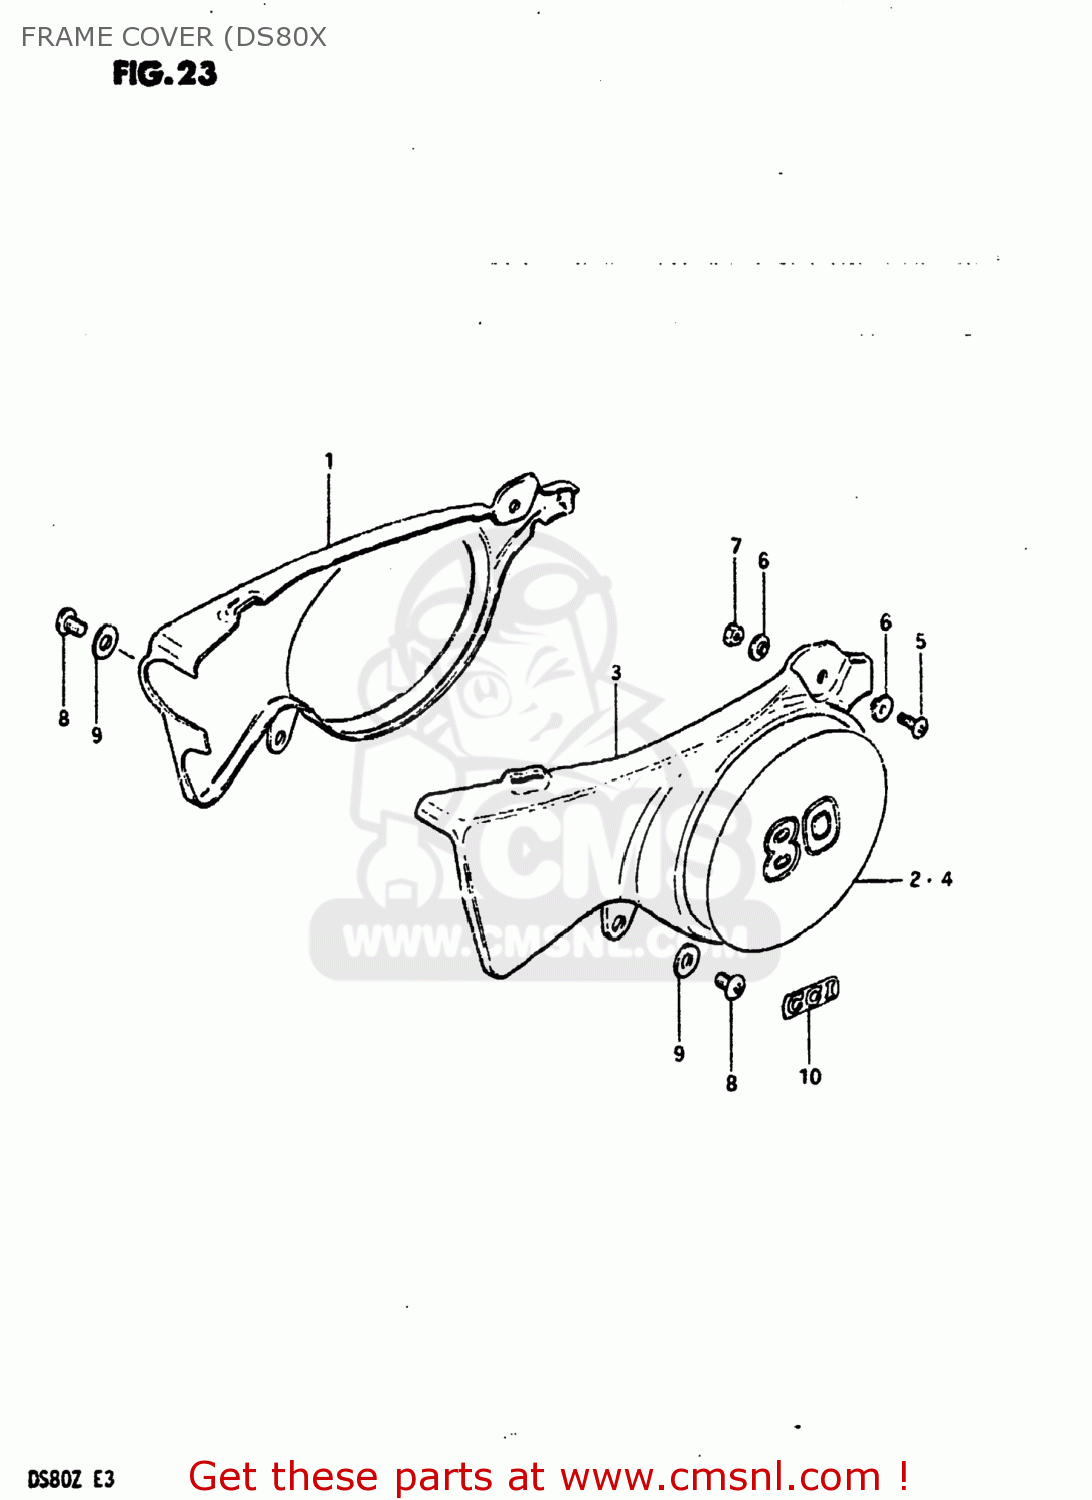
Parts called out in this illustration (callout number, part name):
1	COVER,FRAME,RIGHT
2	EMBLEM
3	COVER,FRAME,LEFT
4	EMBLEM
5	SCREW
6	WASHER
7	NUT
8	SCREW
9	WASHER
10	EMBLEM,CCIS
